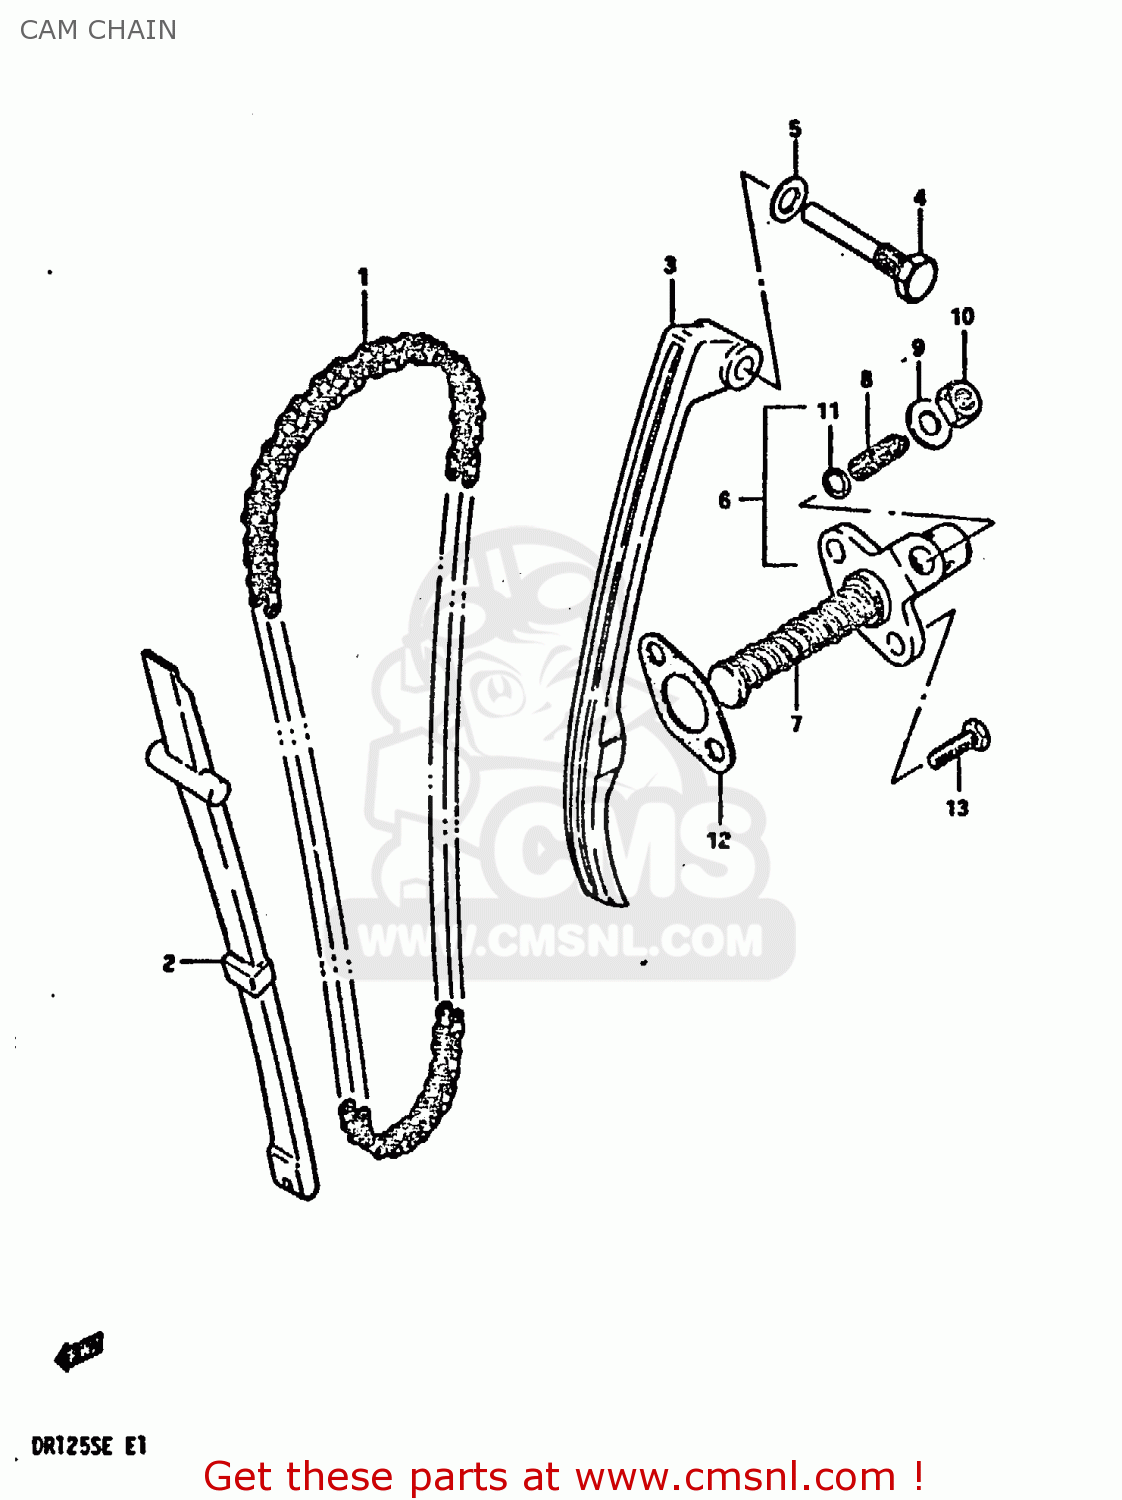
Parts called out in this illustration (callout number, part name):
1	CHAIN,CAMSHAFT DRIVE
2	GUIDE,CAM CHAIN
3	TENSIONER,CAM CHAIN
4	BOLT,CAM CHAIN TENSIONER
5	GASKET 8.2X14X1 (NAS)
6	ADJUSTER ASSEMBLY,TENSIONER
7	SPRING
8	SCREW
9	WASHER
10	NUT
11	O RING(D:1.9,ID:5.7)
12	GASKET,TENSIONER ADJUSTER (NAS)
13	BOLT
